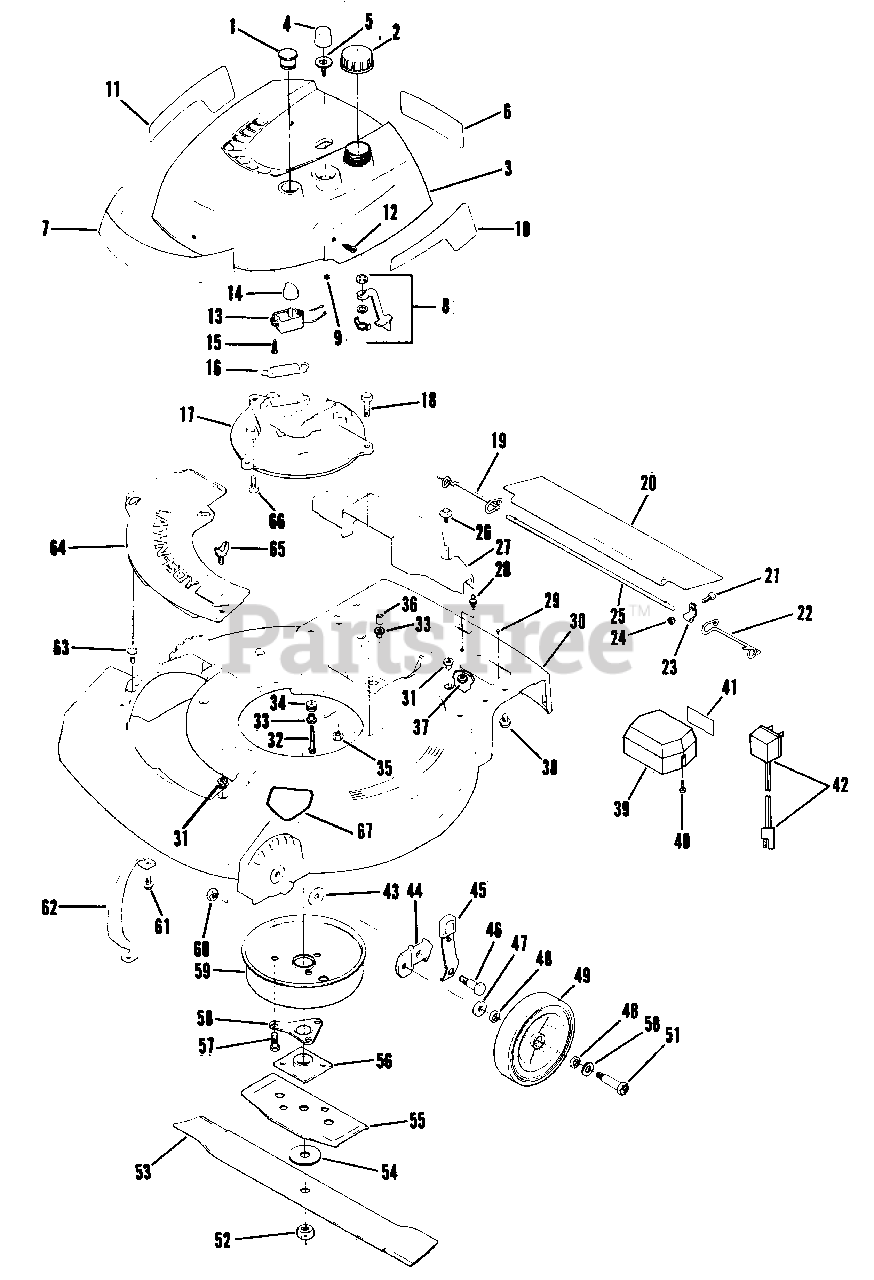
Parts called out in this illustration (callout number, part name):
1	Plug
2	Fuel Cap
3	Shroud-Engine
4	Bulb-Primer
5	Base-Primer
6	Decal-Instructions
7	Decal-Lawn-Boy
8	Fuel Shut-Off Assembly
9	Nut-Primer Base
10	Decal-L.H. 21"
11	Decal-R.H. 21"
12	Screw-Shroud Mounting
13	Switch-On-Off
14	Knob-Switch
15	Screw
16	Gasket-Exhaust
17	Plate-Muffler
18	Screw-Muffler Plate to Housing
19	Spring-R.H.
20	Shield-Trailing
21	Screw
22	Spring-L.H.
23	Clamp
24	Nut
25	Rod-Trailing Shield
26	Screw-Axle Cover Mounting
27	Cover-Drive Axle
28	Ball Stud-Battery Mounting
29	Screw-Model Plate Mounting
30	Housing
31	Grommet
32	Screw-Sems
33	Spacer
34	Grommet
35	Nut-Muffler Plate to Housing
36	Spacer
37	Nut-Ball Stud
38	Screw-Handle Bracket to Housing
39	Battery Box & Battery Pack Assembly
40	Screw
41	Decal
42	Charger-Battery
43	Washer
44	Brcket-Wheel Height Adjustment
45	Knob & Spring Assembly
46	Shoulder Bolt
47	Washer
48	Washer-Felt
49	Wheel-Front
50	Washer
51	Bolt-Wheel-Front
52	Nut-Blade
53	Blade-21"
54	Washer-Blade
55	Stiffener-blade
56	Collar & Plate Assembly
57	Screw
58	Support-Crankshaft
59	Muffler Cover Assembly
60	Nut
61	Screw-Sems
62	Toe Bar
63	Screw-Sems-Plate & Chute Mounting
64	Cover Plate
65	Wing Screw
66	Screw-Muffler Plate to Block
67	Decal-Blade Contact Warning
